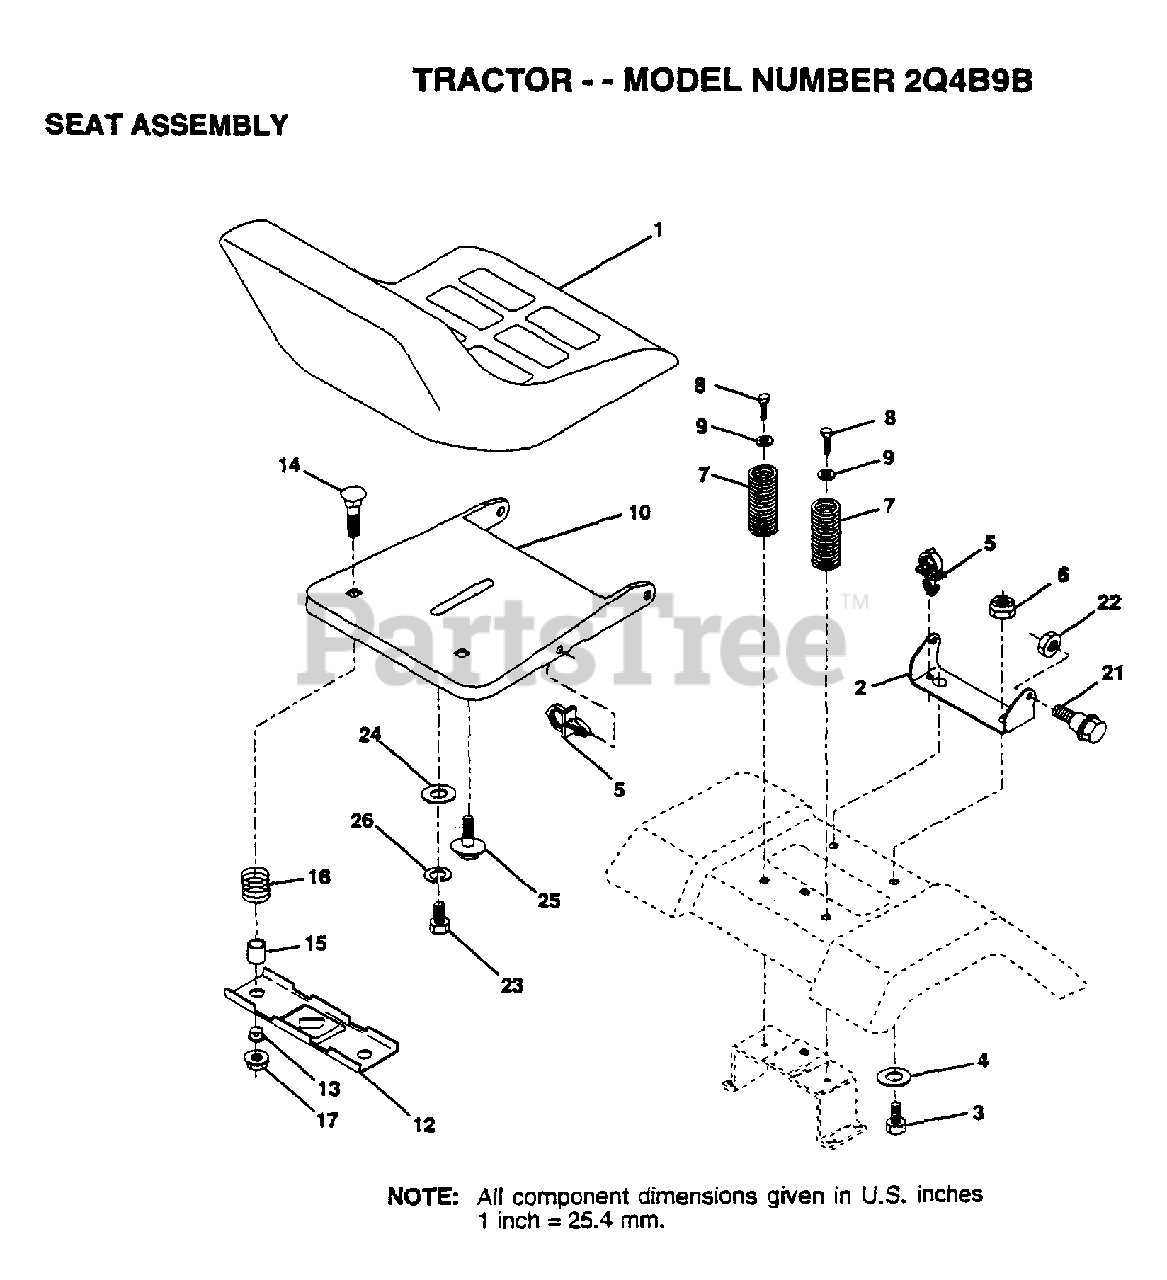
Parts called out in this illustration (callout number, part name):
2	BRACKET PVT SEAT
3	BOLT
4	WASHER PM
5	CLIP.PUSH-IN.HING
6	NUT
7	SPRING COMPRESSIO
8	SCREW GTV
9	WASHER
12	BRKT SWITCH
13	BUSHING
15	SPLIT SPACER
16	SPRING
21	BOLT.SHLD.5/16-18
22	NUT
23	BOLT
24	WASHER
25	"BOLT,SHOULDER"
26	LOCKWASHER
